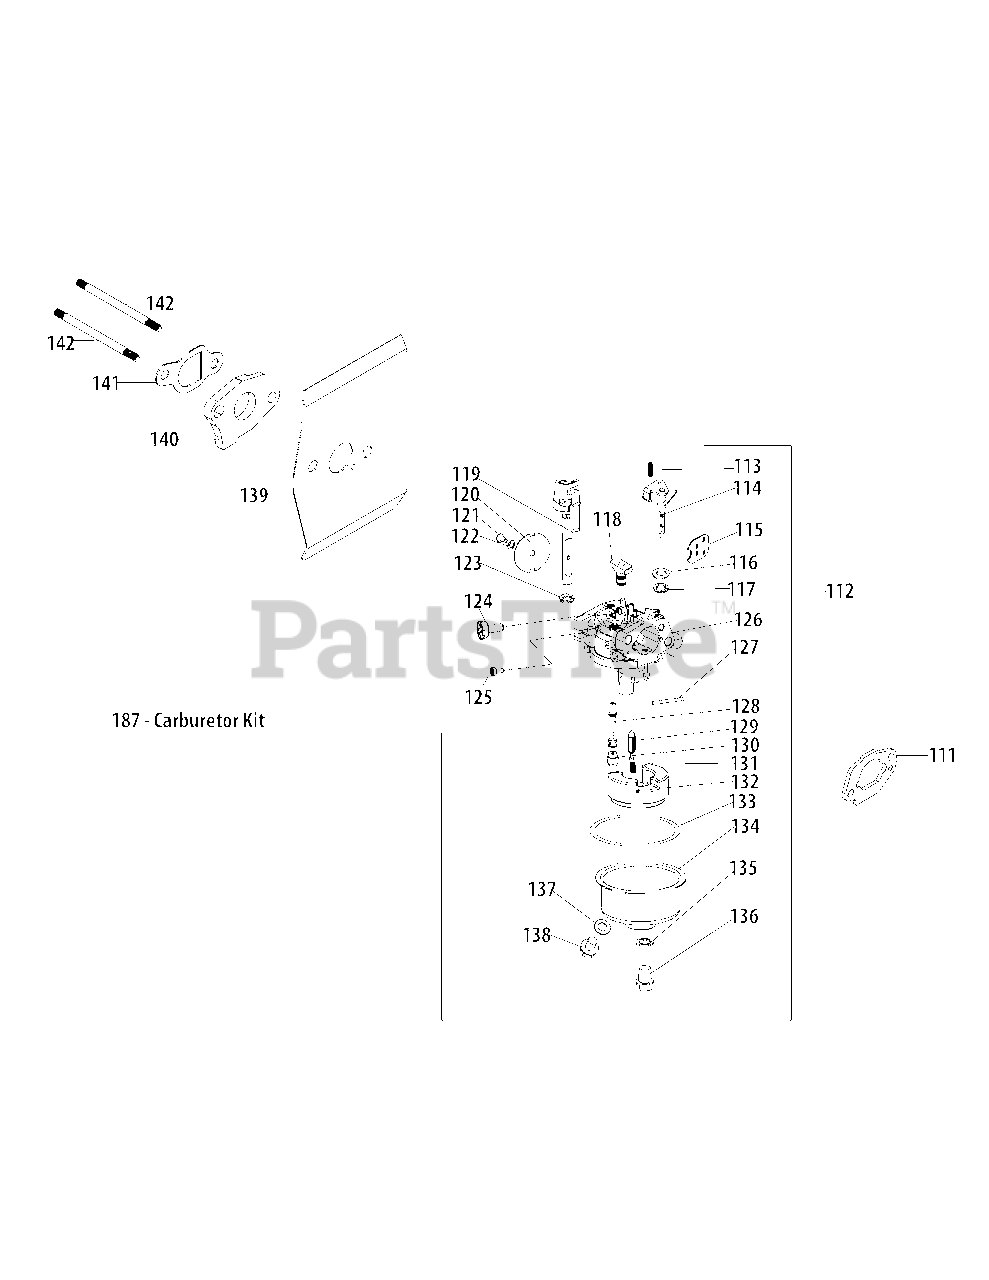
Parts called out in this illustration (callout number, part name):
111	Carburetor Gasket Plate
112	Carburetor Assembly
113	Detent Spring
114	Choke Shaft
115	Choke Plate
116	Choke Shaft Washer
117	Choke Shaft Fiber O-Ring
118	Idle Jet Assembly
119	Throttle Shaft
120	Throttle Plate
121	Screw M3X6 Throttle Plate
122	Throttle Plate Lock Washer
123	Throttle Shaft Fiber O-Ring
124	Idle Speed Adjusting Screw
125	Idle Mixture Screw
126	Carburetor Body
127	Float Pin
128	Emulsion Tube
129	Needle Valve
130	Main Jet
131	Needle Valve Spring
132	Float
133	Fuel Bowl O-Ring
134	Fuel Bowl
135	Fuel Bowl Gasket
136	Fuel Bowl Mounting Bolt
137	Fuel Drain Plug Gasket
138	Fuel Drain Plug
139	Carburetor Gasket
140	Carburetor Insulator
141	Carburetor Insulator Gasket
142	Carb Stud M6X92
187	Carburetor Kit - Major
